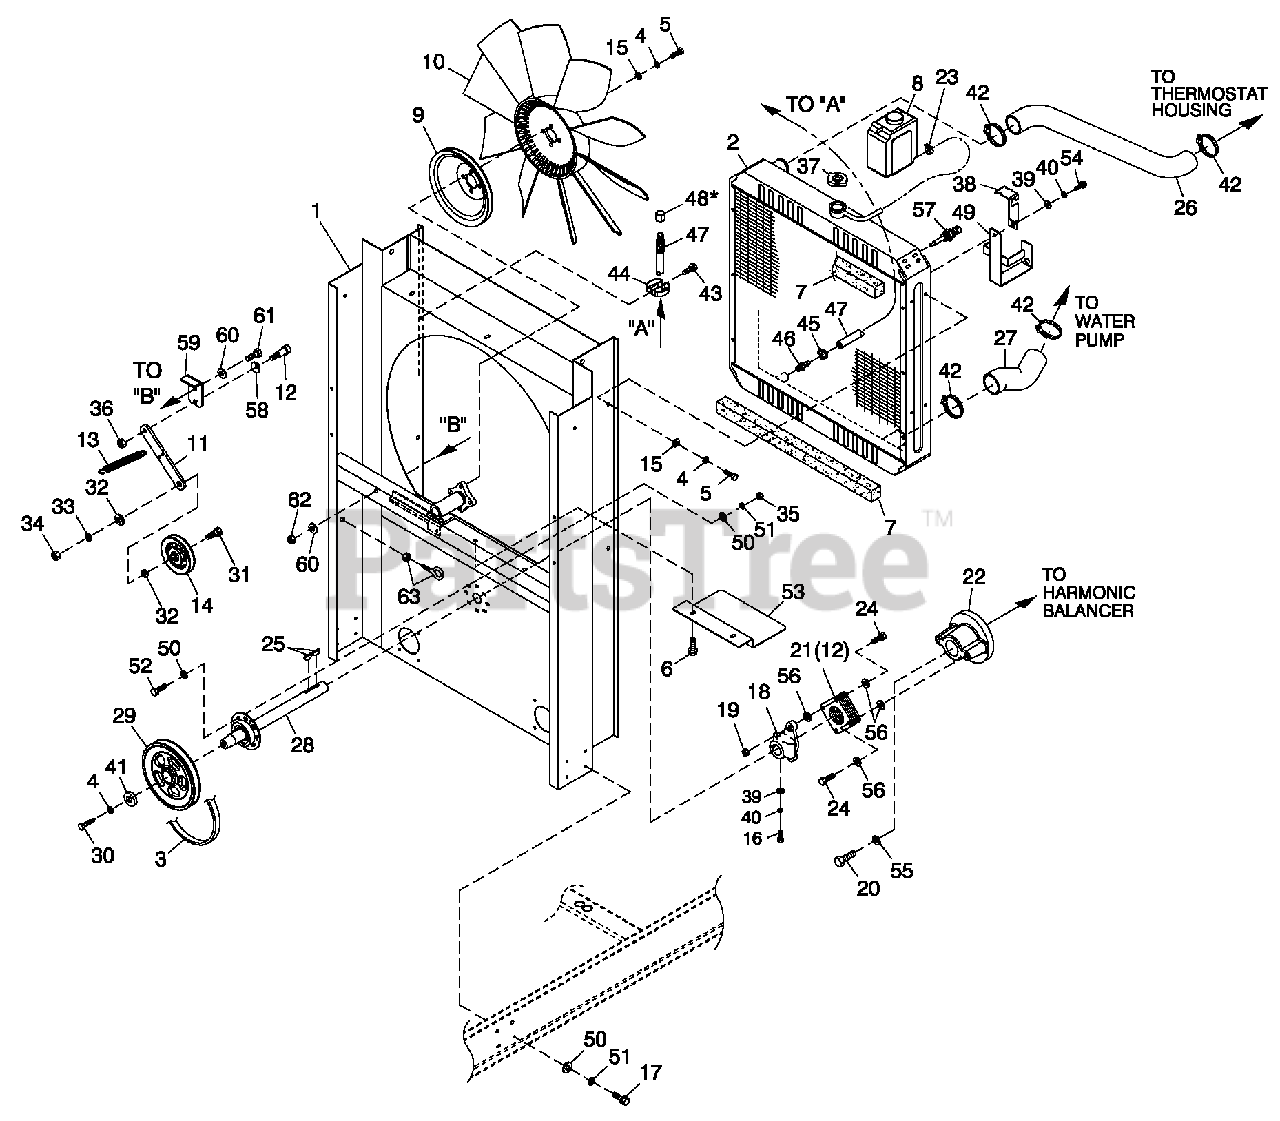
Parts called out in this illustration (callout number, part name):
1	WELDMENT RADIATOR SUPPORT150
2	RADIATOR 680 X 680 X 70 CPL
3	V-BELT 31/64" X 62-3/8"
4	WASHER LOCK M10
5	SCREW HHC M10-1.5 X 20 G8.8
6	SCREW THF M6-1 X 16 N WA Z/JS
7	TAPE FOAM 1 X 1 (26.75" LG)
8	TANK COOLANT RECOVERY
9	PULLEY FAN V-GROOVE 9"
10	FAN 26" LH ROTATION
11	FLAT TENSIONER ARM
12	SHOULDER BOLT 3/8 X 1/2"
13	SPRING TENSION CPL
14	PULLEY V-BELT 4" FLANGED
15	WASHER FLAT 3/8-M10 ZINC
16	SCREW HHC M8-1.25 X 35 G8.8
17	SCREW HHFC M6-1.0 X 20 G8.8
18	HUB FLEX PLATE
19	NUT HEX LOCK 5/16-24 NY INS
20	SCREW HHC M12-1.5 X 60 G8.8
21	DISK FLEX
22	COUPLING FLEX HUB MACHINED
23	CLAMP HOSE BAND 1/4
24	SCREW HHC 5/16-24 X 1.124
25	KEY WOODRUFF 4 X 19D
26	HOSE RADIATOR UPPER CPL
27	HOSE LOWER RAD CPL C5 6.8L
28	ASSY BRG/SHAFT CPL FANDRIVE
29	PULLEY 5.5" DIA MACHINED (5.4L 80KW & 6.8L 150KW)
30	SCREW HHC M10-1.5 X 30 G8.8
31	SCREW HHC 1/2-13 X 2" G8
32	WASHER FLAT 1/2 ZINC
33	WASHER LOCK 1/2
34	NUT HEX 1/2-13 STEEL
35	NUT HEX M6 X 1.0 G8 YEL CHR
36	NUT HEX LOCK 5/16-18 NY INS SS
37	CAP RADIATOR 13 PSI
38	BRACKET, SIGNAL CONDITIONER
39	WASHER FLAT 5/16-M8 ZINC
40	WASHER LOCK M8-5/16
41	SPACER .5 X 1.5 X .25 STL/ZINC
42	CLAMP HOSE #28 1.32-2.25
43	SCREW HHTT M4-0.7 X 8 BP
44	SPRING CLIP HOLDER .37-.62
45	CLAMP HOSE .38-.87
46	BARBED STR 3/8 NPT X 3/8
47	HOSE DRAIN ASSY 28"
48	CAP HEX 1/4 NPT BRASS
49	BRACKET COOLANT TANK
50	WASHER FLAT 1/4-M6 ZINC
51	WASHER LOCK M6-1/4
52	SCREW HHC M6-1.0 X 20 G8.8
53	SHIELD RADIATOR C5
54	SCREW HHC M8-1.25 X 20 G8.8
55	WASHER LOCK M12
56	WASHER FLEX (THIN)
57	PROBE, COOLANT LEVEL 3/8 NPTF
58	WASHER BELLEVILLE .75X.38X.028
59	BENT 90 TENSIONER ARM SUPPORT
60	WASHER FLAT 5/16-M8 ZINC
61	SCREW HHC M8-1.25 X 75 C8.8
62	NUT HEX LOCK M8-1.25 NY INS
63	EYEBOLT 3/8-16 X 3.5" TURNED
